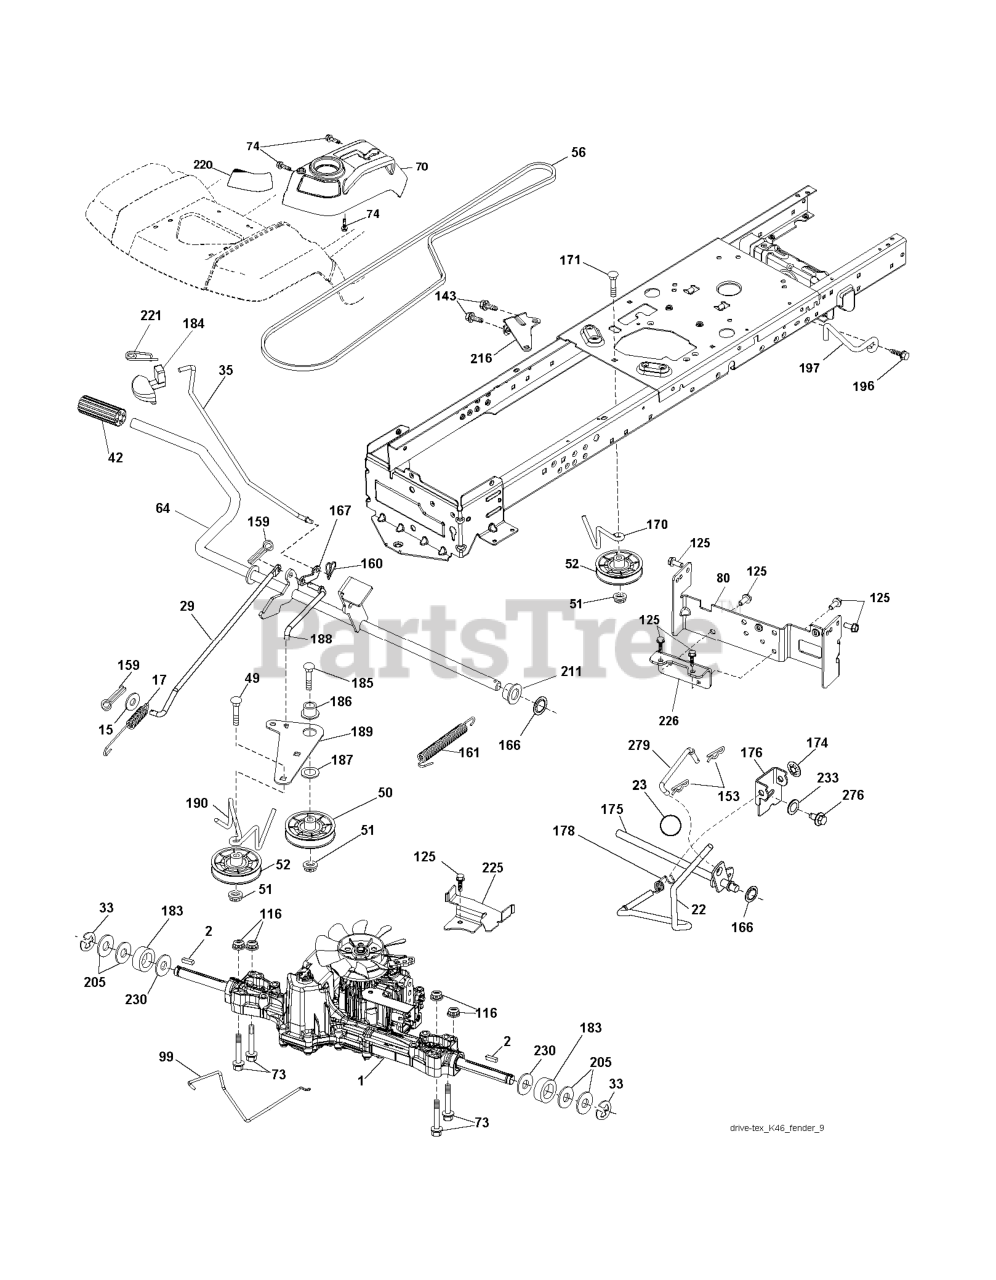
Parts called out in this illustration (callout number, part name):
2	SQUARE KEY
15	WASHER
17	SPRING.BRAKE.K46.GREEN
22	ROD.SHIFT.FENDER.STGT.
23	KNOB.DUCKHEAD.1/2
29	ROD.BRAKE.K46
35	ROD.BRAKE.PARKING.GT.H
42	PEDAL COVER T
50	IDLER.FLAT.910.OFFSET
51	NUT LOCK FLG 3/8-16 UNC
52	IDLER.V-GROOVE.910.OFFSET
56	V-BELT.MOWER.92.40.42/K46
64	SHAFT.ASM.PEDAL.BRAKE.
70	RP CONSOLE.ASM.HYDO.HUSQ.
73	BOLT HEX 5/16-18 GR 5
74	SCREW.HI-LO.CONSOLE
80	STRAP TORQUE
99	ROD.SPRING.BYPASS.K46.LT.Z
116	NUT LOCK HEX FLANGE 5/16-18
125	SCREW
143	Screw 5/16-18 x 1/2 Hex, Self Tapping 5/16-18 x 1/2
153	RETAINER M
159	COTTER PIN
160	RETAINER CLIP
161	SPRING, RETURN LT
166	NUT.PUSH.625
167	LATCH.BRAKE.SPRING
170	KEEPER.V-IDLER.CENTER.
174	NUT.PUSH.500.2006
175	SHAFT ASM SHIFT
176	ARM.CLEVIS.ROD.SHIFT
178	SPRING.SHIFT.GT2006
183	SPACER AXLE
184	HANDLE.PARKG.BRK.HUSQ X667
186	SPACER.RETAINER
187	WASHER 12/32X2X10GA
188	RP.LINK.CLUTCH.GROUND.DRIVE
189	BELLCRANK.GROUND.DRIVE.TEX.
190	KEEPER.BELLCRANK.DRIVE
196	SCREW 3/8-16X1
197	LINK.CLUTCH.ANIT-ROTAT
211	BUSHING.SHAFT.BRAKE.HAND
216	BRACKET.PULLEY.IDLER.W/TEX
220	REFLECTOR.RH.TEX GT
221	RETAINER.SPRING.CLIP.H
225	KEEPER.BELT.TRANSAXLE.K46
226	BRACKET.MOUNT.TORQUE.K46.TLT
230	WASHER.HARDENED
233	WASHER SERRATED
276	BOLT FIN HEX 7/16-14 X 1
279	LINK.SHIFT.T/A.K46.FEND.TX
